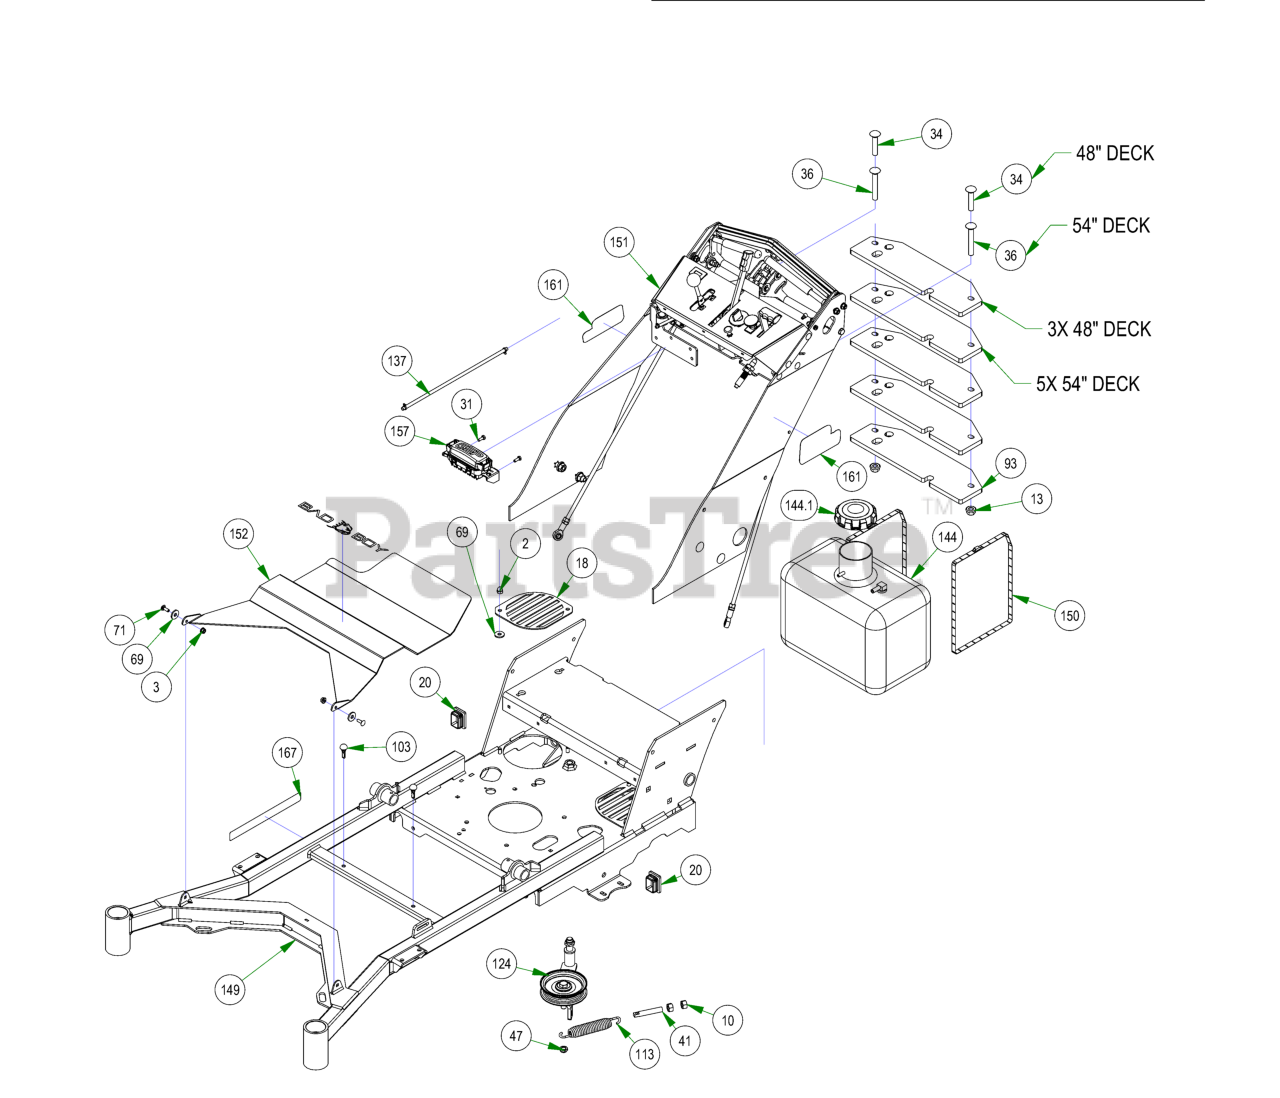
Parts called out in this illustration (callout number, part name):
2	5/16-18 ACORN NUT HIGH-CROWN ZC
3	1/4-20 NYL INSERT FLANGE LOCKNUT ZINC
10	1/2-13 HEX NUT ZINC
13	1/2-13 NYLON INSERT FLANGE LOCKNUT ZINC
16	5/16-18 NYLON INSERT JAM LOCKNUT ZINC
18	Walk Behind Bolt on Fan Cover
20	1 1/2 X 2 Plug For .120 Tubing
31	M6-1.0 X 16MM DIN 933 HEX TAP BOLT (CL 8.8) ZINC
34	2 1/2 x 1/2 Carriage Bolt
36	1/2-13 X 3-1/2 CARRIAGE BOLT (GR.5) ZINC
41	All Thread
47	1/2-13 NYLON INSERT JAM LOCKNUT ZINC
60	1/4-20 X 3/4 HEX CAP SCREW (GR.5) ZINC
69	.360 ID X .983 OD X .120 THICK FLAT WASHER NYLON BLACK
71	1/4-20 X 3/4 CARRIAGE BOLT (GR.5) ZINC
72	5/16 USS FLAT WASHER (7/8 OD) ZINC
93	2020 Walk Weight Plate
103	2023 Floor Board Rubber Bumper
113	2009 Deck/Pump Idler Spring
124	ZT Pump Idler
137	15" Revolt Fuel Line Assembly
144	5 Gal Black Gas Tank w/gauge
149	2023 Walk Frame
150	Tank Strap
151	23WB Podium Assembly
152	2023 WB V2 Floorboard
157	2020 Electric Start Walk Behind Harness
161	2018 Walk Behind 603cc Back Plate Cluster
167	Outlaw Warning Decal
169	Flying Bulldog Front Bumper Decal
